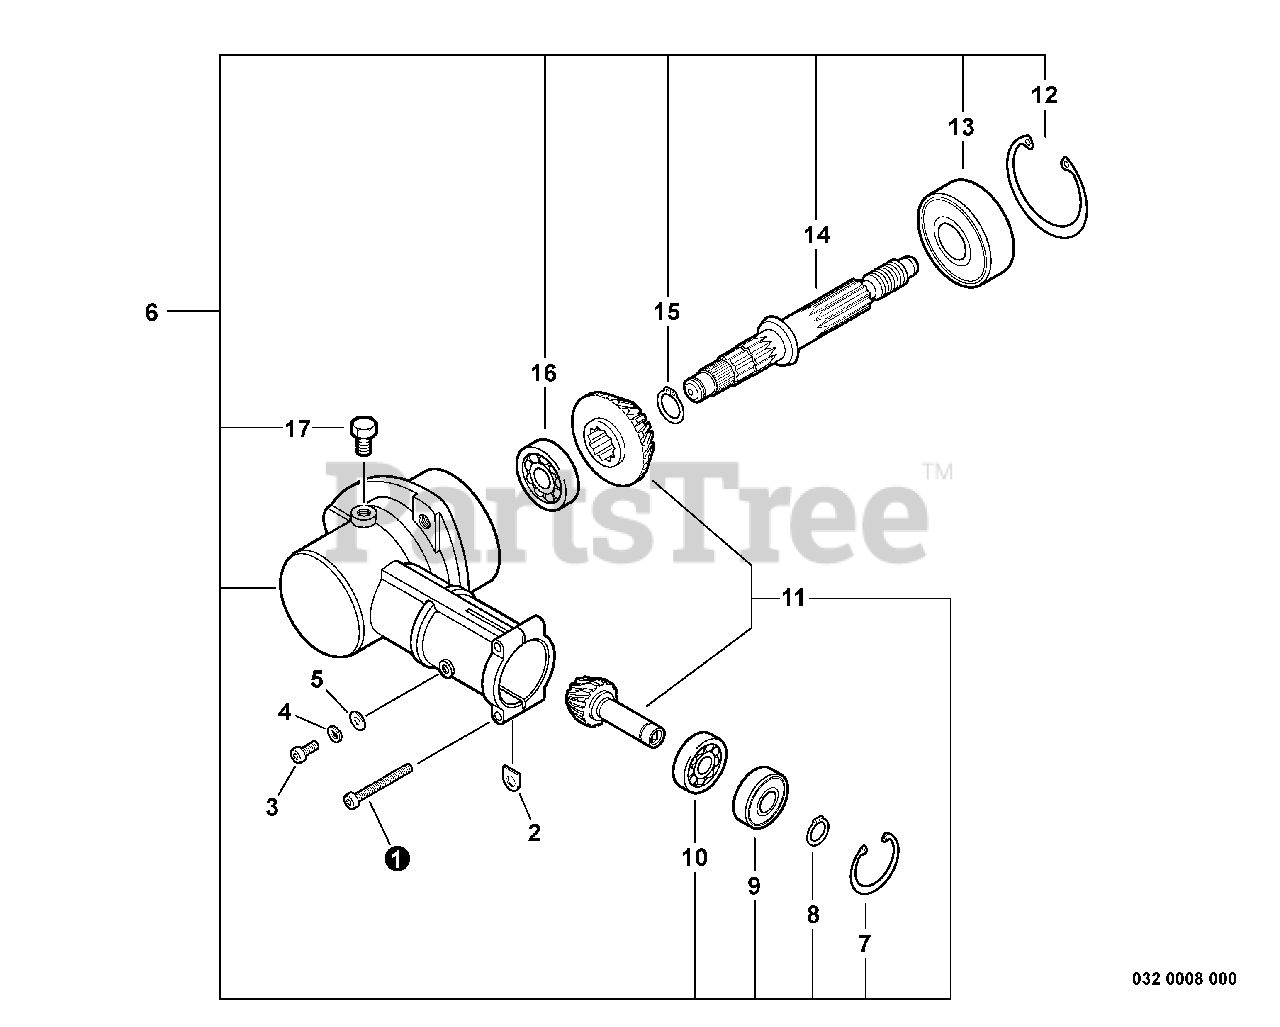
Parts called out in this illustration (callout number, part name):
1	SCREW - 5X25
3	SCREW - 5X12
4	LOCKWASHER - 5
5	WASHER - 5
6	GEAR CASE ASSY
7	RING, RETAINING - 22
8	RING, RETAINING - 10
9	BEARING, BALL - 6900Z
10	BEARING, BALL - 6900
11	GEAR SET
12	RING, RETAINING - 42
13	BEARING, BALL - 609
14	GEAR - SHAFT
15	RING, RETAINING - 12
16	BEARING, BALL - 629
17	BOLT - 8X8
